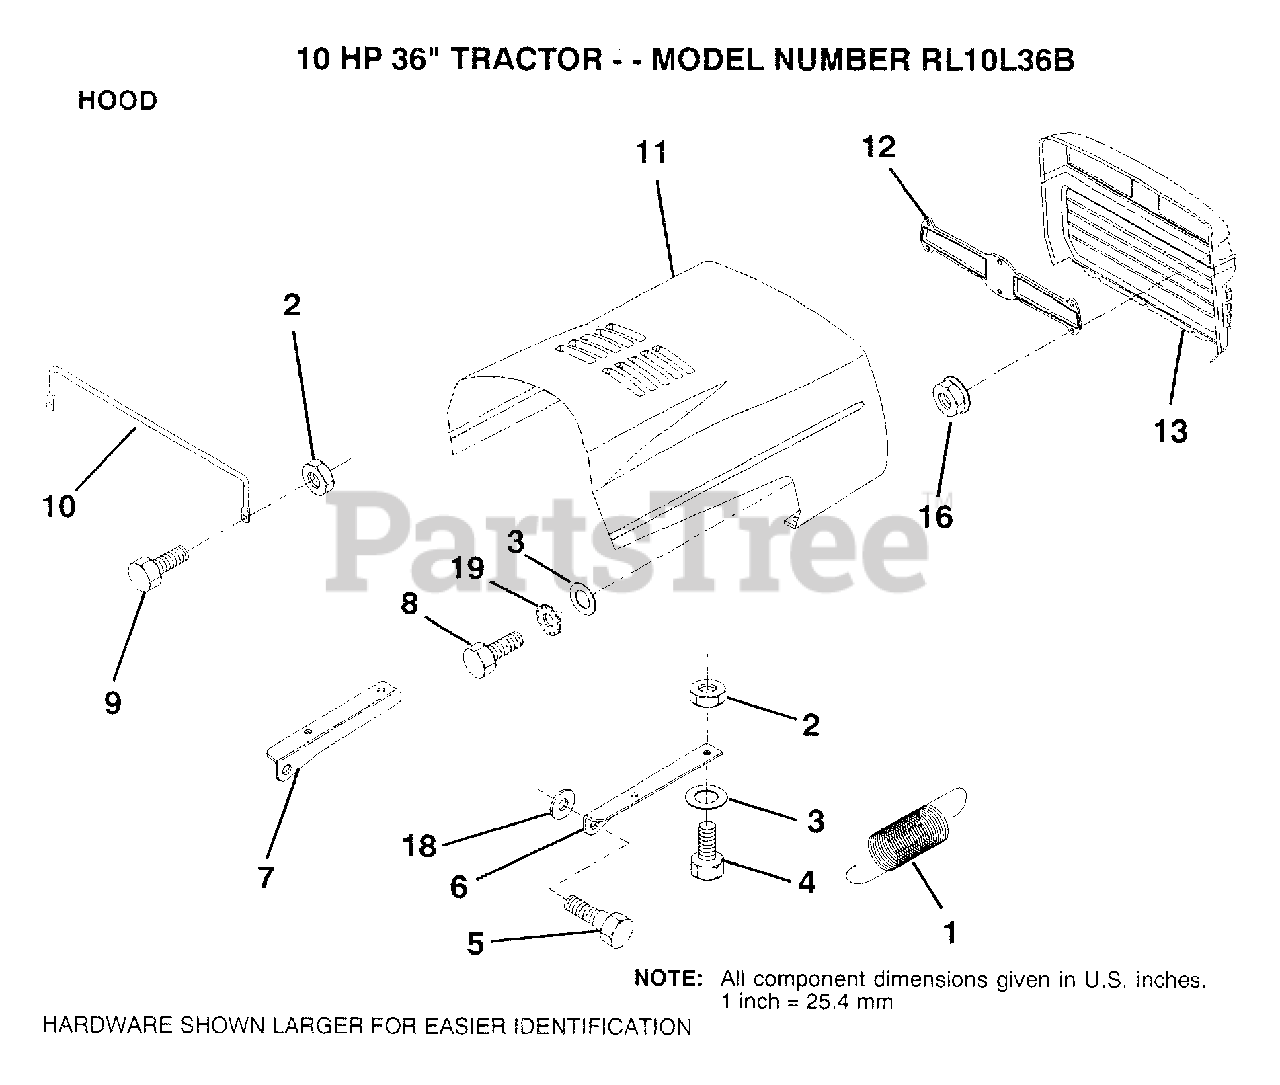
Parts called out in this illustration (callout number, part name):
1	EXT SPRING
2	NUT
3	WASHER
4	BOLT
6	BRKT HOOD RH
7	BRKT HOOD LH
10	"BRACE,HOOD"
11	HOOD
16	NUT
18	WASHER
19	LOCKWASHER GT
